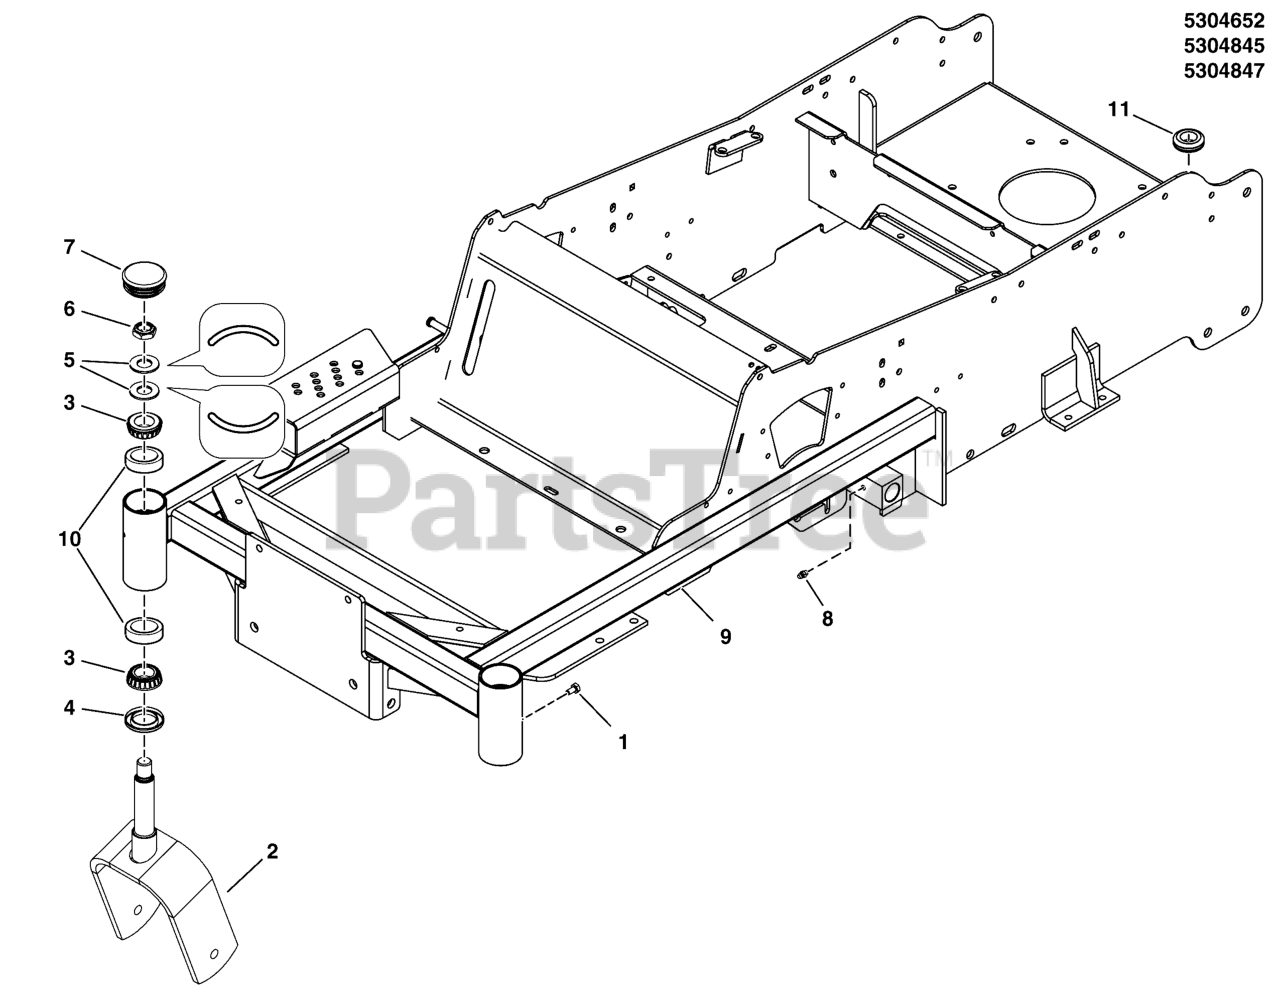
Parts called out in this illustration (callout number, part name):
1	BOLT, 1/4-28 X 1/2, GD5 YZ
2	WELD, CASTER YOKE - RED
3	BEARING, TAPERED ROLLER, 1"
4	SEAL, GREASE
5	WASHER, BELLEVILLE - 1.500 X .755
6	NUT, 3/4-16, HEX JAM NYLON LOCK
7	CAP, GREASE, LOW PROFILE
8	GREASE FITTING, 1/4-28 Straight
9	WELD, MAIN FRAME, 36" - RED
9	WELD, MAIN FRAME, 48" - RED
10	CUP, BEARING (SV)
11	GROMMET, 7/8"
